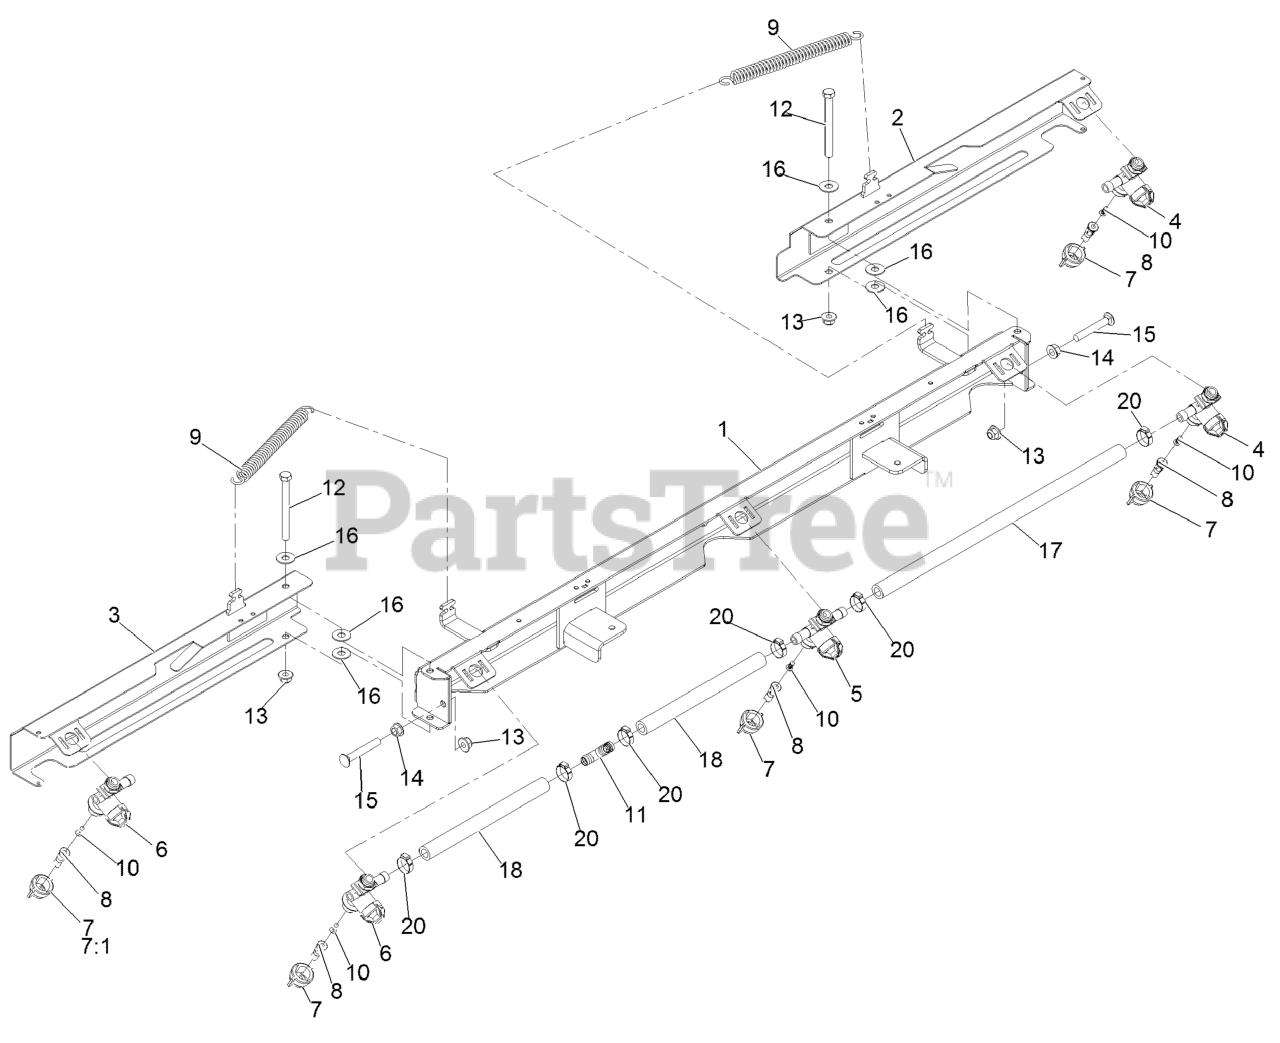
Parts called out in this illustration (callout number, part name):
1	BOOM-CENTER
2	BOOM-WING, RT
3	BOOM-WING, LT
4	BODY-NOZZLE, RIGHT
5	BODY-NOZZLE, CENTER
6	BODY-NOZZLE, LEFT
7	CAP-NOZZLE
7:1	SEAT-GASKET
8	TIP-SPRAY, 025
9	SPRING-EXTENSION
10	STRAINER-NOZZLE, 50M 5PSI
11	FITTING-TEE, BARB
12	SCREW-HH
13	Nut-Hex Flange
14	Nut-Hex Flange
15	SCREW-CARR
16	WASHER-FLAT
17	Hose-Spray
18	Hose-Spray
20	CLAMP-OETIKER, 167
